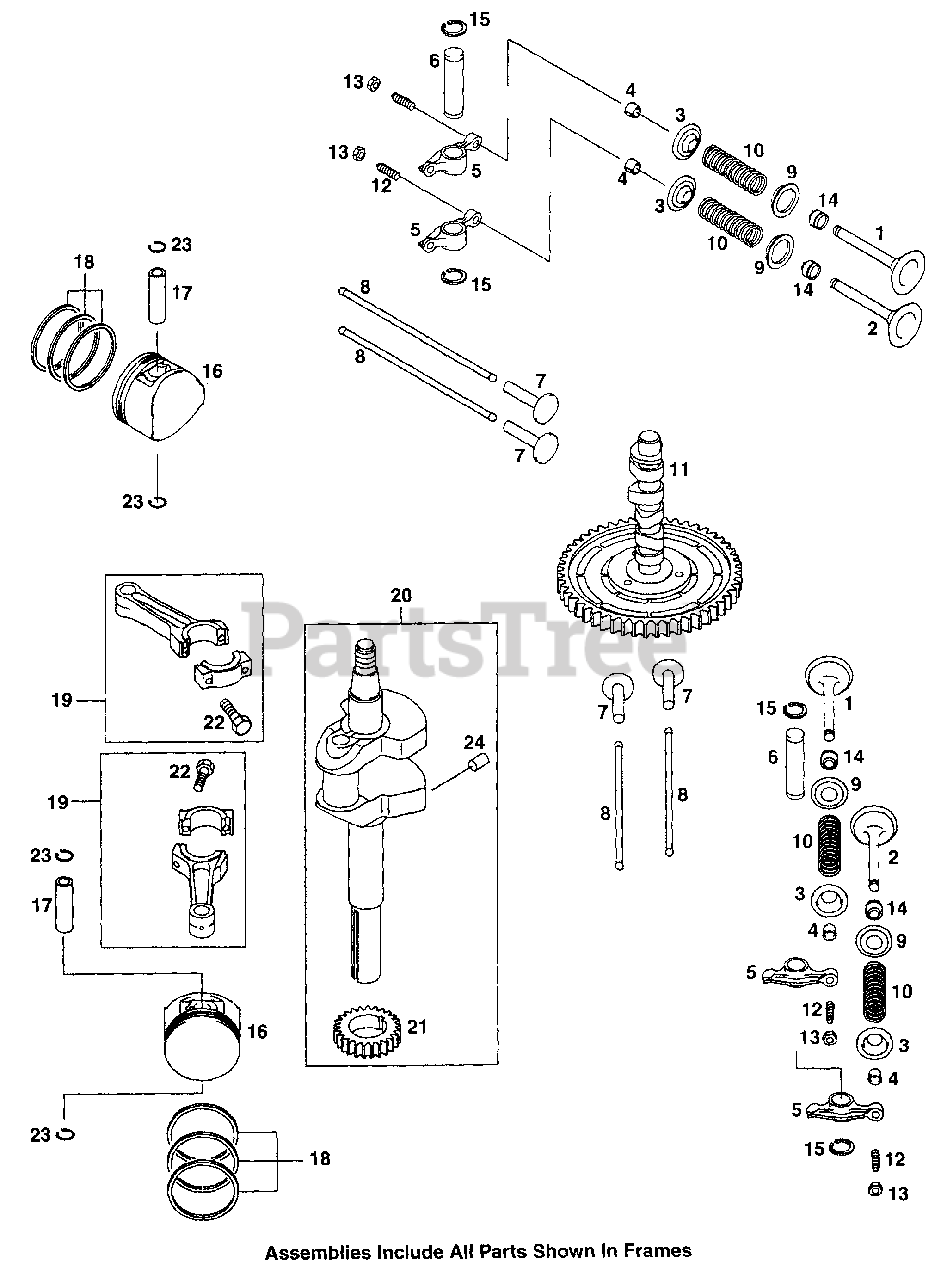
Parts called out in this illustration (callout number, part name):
1	Intake Valve
2	Exhaust Valve
3	Valve Spring Retainer
9	Spring Retainer
11	Complete Camshaft
18	Piston Ring Set
19	Connecting Rod Assembly
20	Crankshaft Assembly
